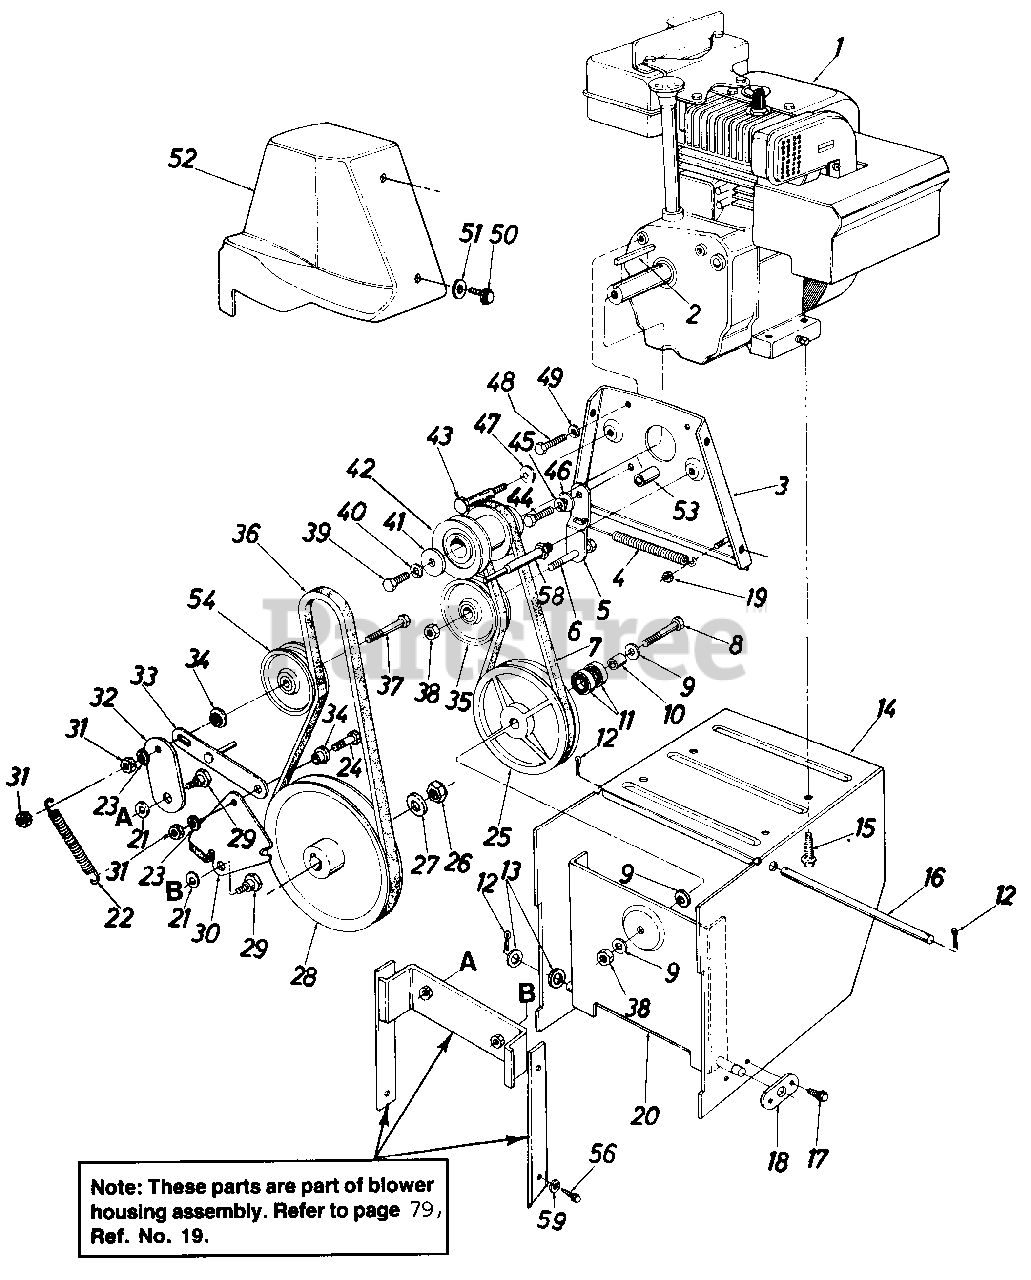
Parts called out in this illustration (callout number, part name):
1	Engine
2	Sq. Key 3/16" x 1.50" Lg.
3	Engine Plate Ass'y.
4	Extension Spring .50" O.D. x 3.97" Lg.
5	Drive Clutch Idler Brkt.
6	Hex Bolt 3/8-24 x 1.25" Lg.
7	'V'-Belt
8	Hex Bolt 3/8-24 x 1.50" Lg.
9	Bell-Wash. .40" I.D. x .88" O.D. x .06
10	Spacer .38" I.D. x .62" O.D. x.75" Lg.
11	Ball Brg. .62" I.D. x 1.38" O.D. x .44
12	Cotter Pin 3/32" Dia. x .75" Lg.
13	Fl-Wash. .53" I.D. x 1.00" O.D. x .125
14	Frame Ass'y.
15	Hex Wash. Hd. Self-Tap Scr. 3/8-16 x 1.25" Lg.
16	Shaft .50" Dia. x 9.50" Lg.
17	Hex Wash. Hd. Self-Tap Scr. 1/4-20 x .50" Lg.
18	Axle Bracket
19	Hex L-Nut 1/4-20 Thd.
20	Drive Pulley Support Brkt. Ass'y.
21	Bell-Wash. .40" I.D. x 1.13" O.D.
22	Extension Spring .56" O.D. x 4" Lg.
23	L-Wash. 3/8" I.D.
24	Hex Scr. 3/8-16 x 1.25" Lg.
25	6.00" O.D. Drive Pulley Ass'y.
26	Hex Jam Cent. L-Nut 5/8-18 Thd.
27	Fl-Wash. .64" I.D. x .94" O.D. x .06
28	1/2" V-Pulley .625" I.D. x 7.50" O.D.
29	Shld. Bolt .625" Dia. x .170" Lg.
30	Brake Bracket Ass'y.
31	Hex Ins. L-Nut 3/8-16 Thd.
32	Auger Clutch Idler Brkt.
33	Brake Linkage Ass'y.
34	Shld. Spacer.625" I.D.
35	Fl-Idler Pulley 2.25" O.D.
36	"V"-Belt
37	Hex Bolt 3/8-16 x 2" Lg.
38	Hex Ins. Jam L-Nut 3/8-24 Thd.
39	Hex Bolt 3/8-24 x 1.50" Lg.
40	L-Wash. 3/8" I.D.
41	Bell-Wash. .40" I.D. x 1.25" O.D.
42	Double Groove Engine Pulley
43	Shld. Scr. .498" x 3.0" Lg.
44	Hex Bolt 5/16-24 x 1.00" Lg.
45	L-Wash. 5/16" I.D.
46	Shld. Spacer .27" Lg.
47	Bell-Wash. .40" I.D. x .88" x .06
48	Hex Bolt 5/16-24 x .62" Lg.
49	L-Wash. 5/16" I.D.
50	Hex Wash. Hd. Self-Tap Scr. 1/4-20 x .50" Lg.
51	Fl-Wash. .28" I.D. x .75" O.D. x .06
52	Belt Cover
53	Spacer
54	Fl-Idler Pulley 2.75" O.D.
56	Hex Wash. Hd. Self-Tap Scr. 3/8-16 x .75" Lg.
58	Stud 3/8-16 x 3.37" Lg.
59	L-Wash. 3/8" I.D.-H.D.
